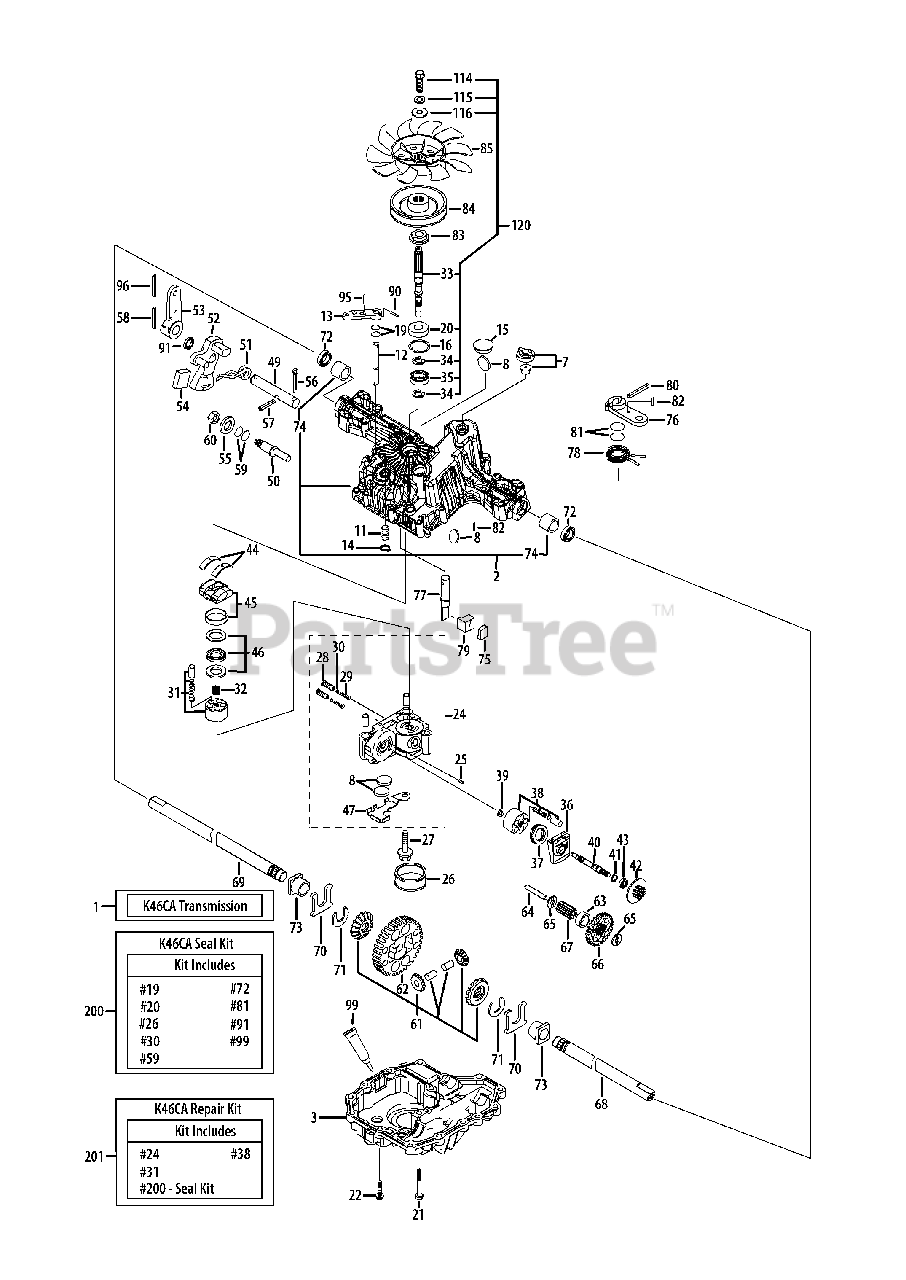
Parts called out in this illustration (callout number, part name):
1	K46CA Transaxle
2	Kit, Upper Case
7	Vent Valve 15
12	Bypass Shaft A
14	Snap Ring 10
15	Sealing Cap 30
16	Snap Ring C 35
19	O-Ring 1A P10A
20	Seal TC 153507
21	Tapping Screw 8 x 55
22	Tapping Screw 8 x 30
24	Kit, Center Case C
26	Filter 105
28	IDS Valve 1.2
30	IDS Filter 300
31	Kit, Cylinder Block (Pump)
34	E-Ring 15
35	Bearing 6202C3
36	Motor Housing
37	Thrust Bearing 51106
38	Kit, Cylinder Block
39	Washer 12 x 24 x 1
41	Snap Ring C15
42	Brake Disc/Motor Gear (11T)
43	Bearing 6202 RSR C3
44	Thrust, Plastic
45	Swash Plate Assembly
46	Kit, Thrust Bearing (Pump)
47	Magnet Holder
49	Control Shaft
51	Torsion Spring, Standard
52	Control Arm A
53	Control Lever F
56	Cotter Pin 1/8" x 3/4"
57	Spring Pin 6 x 36
58	Roll Pin 6 x 40
61	Diff Gear Kit
62	Final Gear (54T)
63	Final Pinion Collar
64	Reduction Shaft
65	Washer 12 x 32 x 3.2
66	Reduction Gear (37T)
67	Final Pinion Gear (10T)
68	Axle Shaft, Left
69	Axle Shaft, Right
70	Thrust Washer
72	Seal 19 x 32 x 8
73	Bushing 19 x 25
74	Bushing 19.05
78	Brake Return Spring
79	Brake Actuator
80	Spring Pin 5 x 32
81	O-Ring 1A P12
82	Spring Pin 4 x 16
83	Spline Collar
90	Spring Pin 3.0A x 20
91	Oil Seal 16 x 22 x 03
95	Spring Pin 3.0A x 16
96	Roll Pin 3.5 x 40
99	Sealant
120	Pump Shaft/Bearing Kit
200	Kit,Seal
201	Repair Kit,
